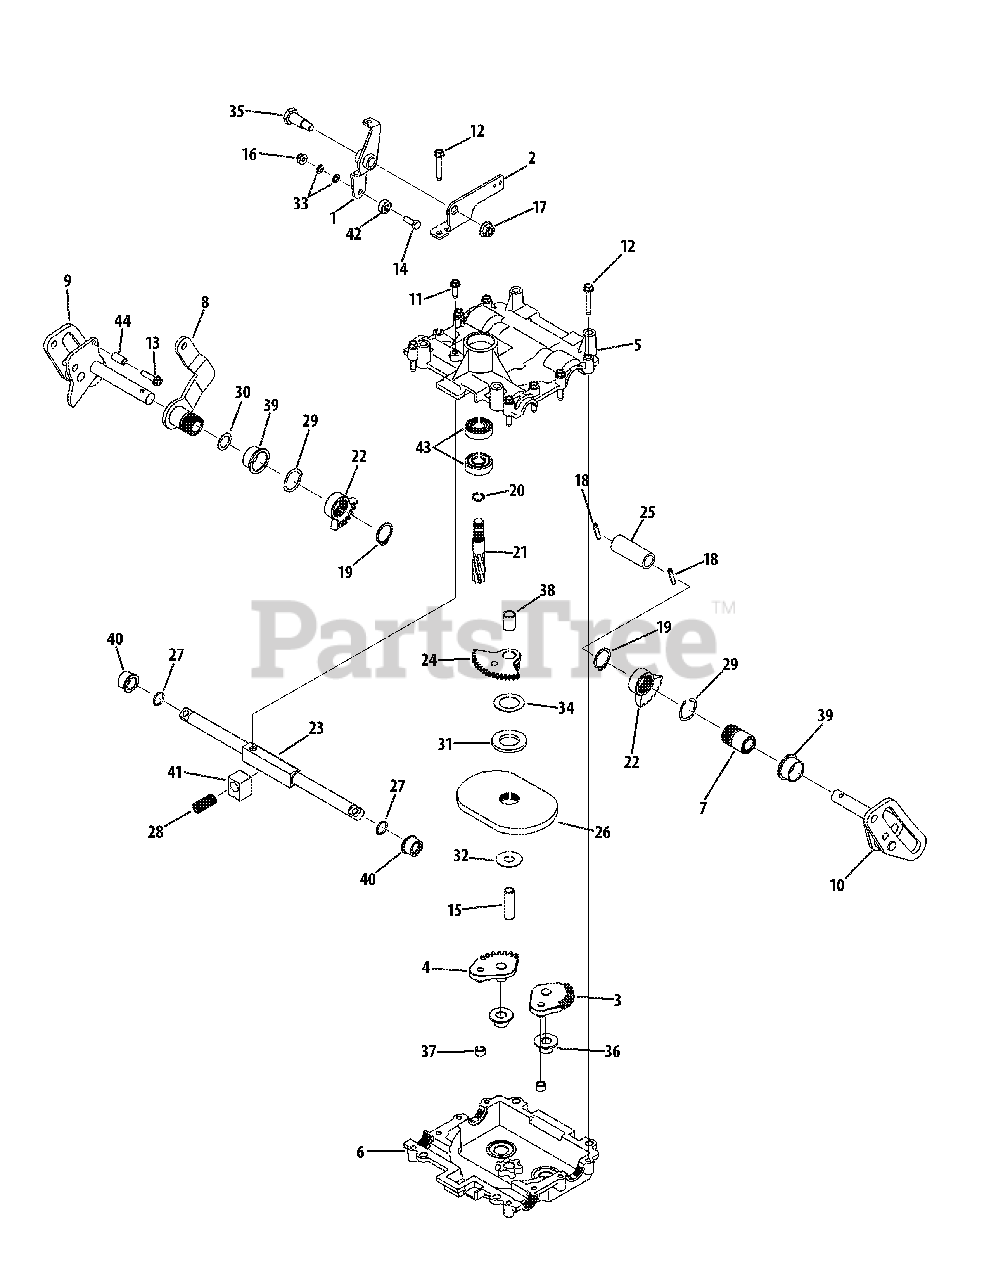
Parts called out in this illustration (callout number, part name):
1	Cam Plate Assembly
2	Neutral Bracket
3	LH Steering Gear Assembly
4	RH Steering Gear Assembly
5	Upper Steering Housing
6	Lower Steering Housing
7	Vertical Hydro LH Arm Assembly
8	Vertical Hydro RH Arm Assembly
9	RH Cam Assembly
10	LH Cam Assembly
11	Hex Washer Screw, 1.4-20 x 0.750
12	Hex Washer Screw, 1.4-20 x 1.500
13	Hex Washer Screw. 1.4-20 x 1.000
14	Hex Screw, 1.4-20 x .75
15	Steering Shaft
16	Flange Lock Nut, 1.4-20
17	Flange Lock Nut, 3.8-16
18	Spirol Pin, 3.16 x 1.00
19	Snap Ring, 1.0
20	Retaining Ring, .56
21	Pinion Gear, 7-Tooth
22	Steering Gear, 26-Tooth
23	Synchro Rack Gear
24	Steering Gear, 53-Tooth
25	Speed Cam Tube
26	Hydro Steering Cam
27	O-Ring, .625 x .07
28	Compression Spring, .531 x 1.25
29	Wave Spring, 24.22 x 32 x 1.98
30	Flat Washer, .635 x .930 x .033
31	Flat Washer, 1.01 x 1.75 x .172
32	Flat Washer, .508 x 1.325 x .040
33	Flat Washer, .260 x .455 x .048
34	Thrust Washer, 1.007 x 1.542 x .03
35	Shoulder Screw, 3.8-16 x .500 x .835
36	Flange Bearing, .5 x .700
37	Sleeve Bearing, .437 x .3425
38	Sleeve Bearing, .623 x .5025 x .800
39	Sleeve Bearing, 1.2 x 1.00
40	Flange Bearing, .625 x .875
41	Rack Caster Bearing
42	Ball Bearing, .25 x .6875 x .25
43	Ball Bearing, .5625 x 1.375 x .4375
44	Spacer, .260 x .375 x .75
